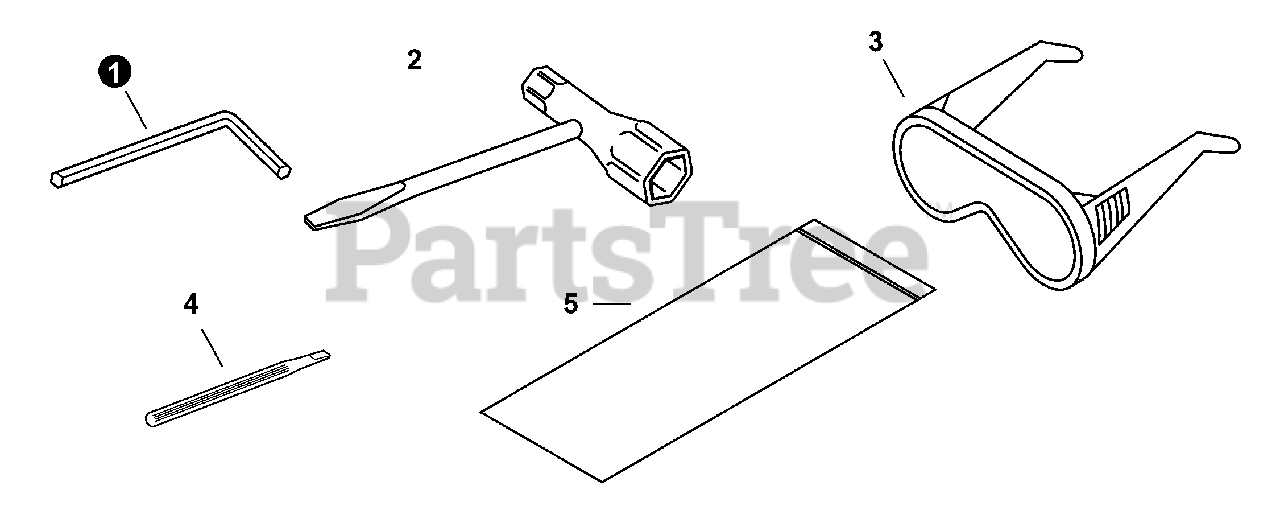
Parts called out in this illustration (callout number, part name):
1	WRENCH, ALLEN 4 MM
2	T-WRENCH 13×19 L= 180
3	GLASSES, SAFETY
4	SCREWDRIVER, PLASTIC
5	BAG, TOOL
